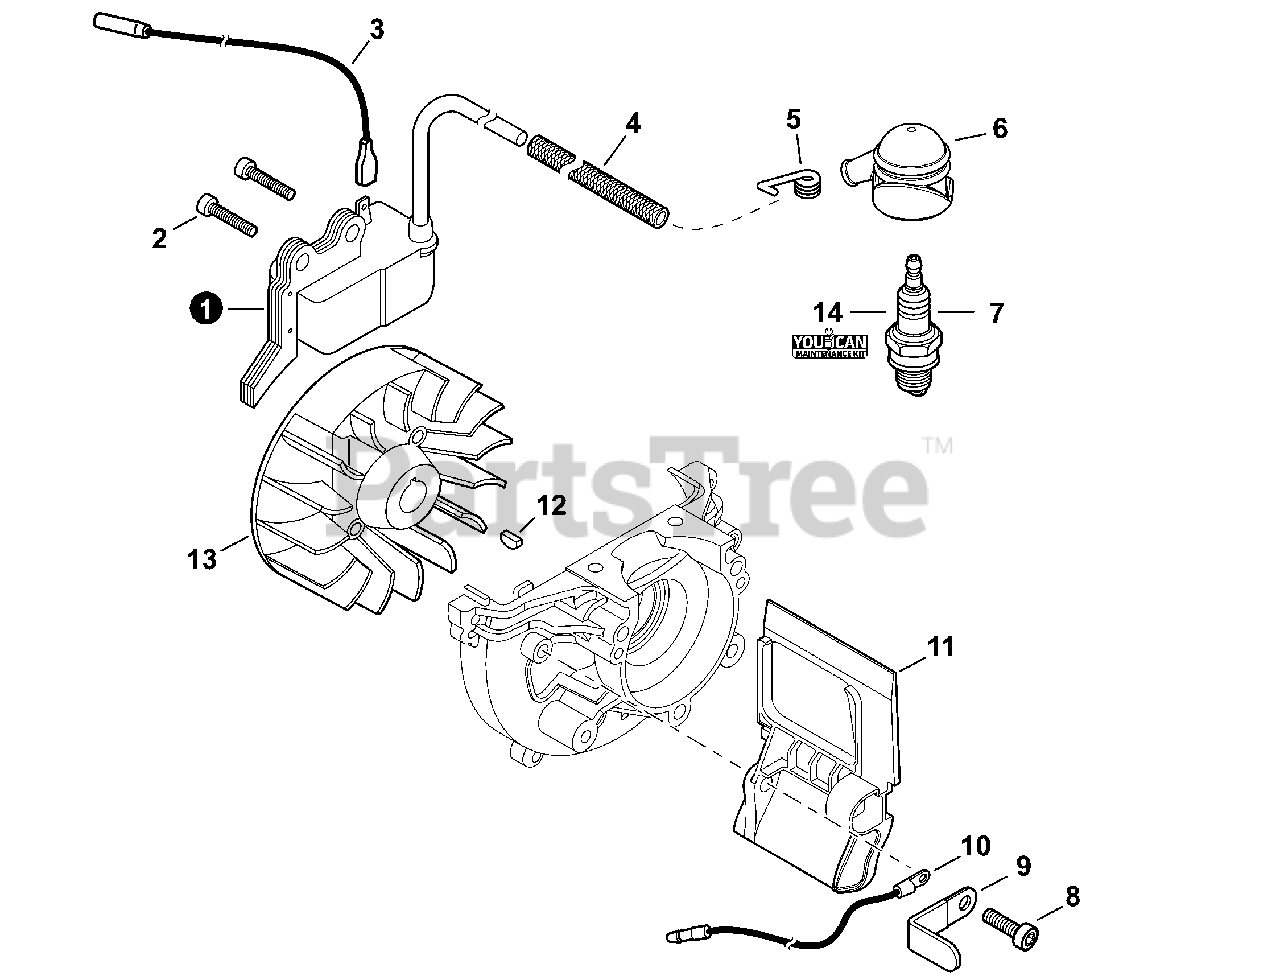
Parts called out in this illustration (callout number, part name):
1	COIL, IGNITION
2	BOLT, TORX 4×20
3	LEAD - IGNITION L= 210
4	TUBE, INSULATOR
5	TERMINAL, SPARK PLUG
6	CAP, SPARK PLUG
7	SPARK PLUG - BPMR8Y
8	BOLT, TORX 5×12
10	LEAD - GROUND L= 115
11	PLATE, INSULATOR
12	KEY, WOODRUFF
13	FLYWHEEL
14	TUNE-UP KIT - YOUCANT
